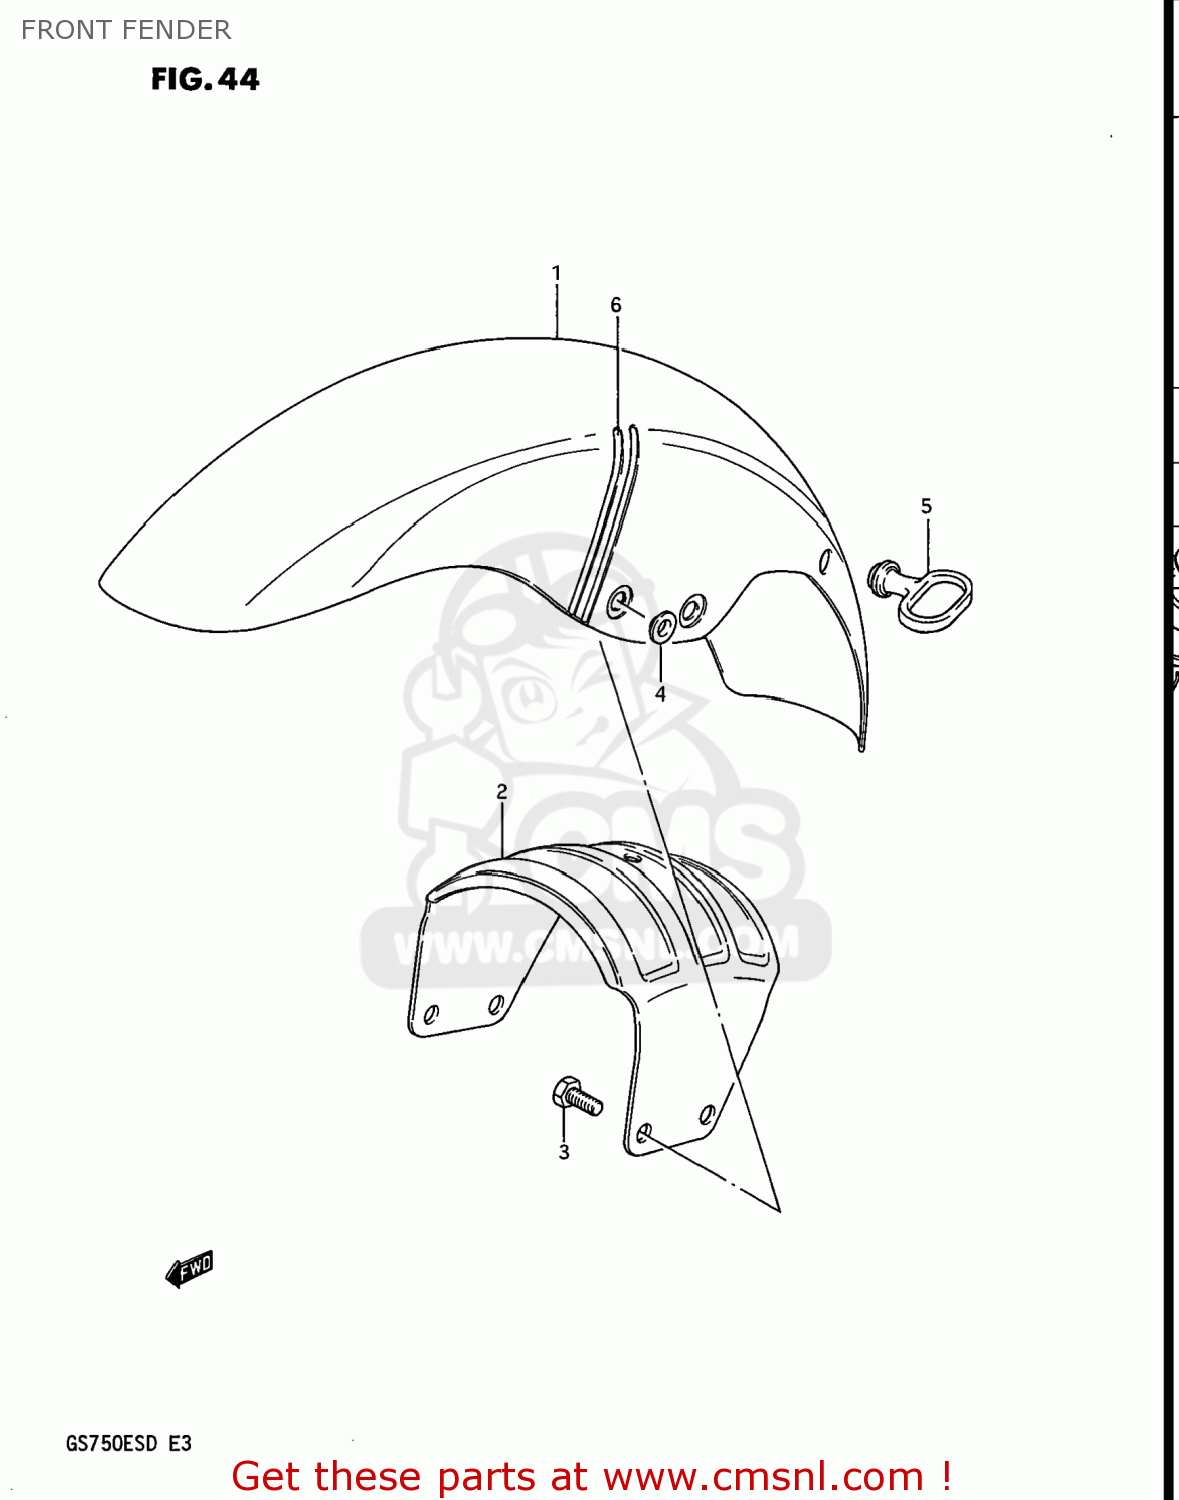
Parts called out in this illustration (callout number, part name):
1	FENDER,FRONT
2	BRACE,FRONT FENDER
3	BOLT 8X16
4	WASHER
5	GUIDE,CABLE
6	DENT,FRONT FENDER
